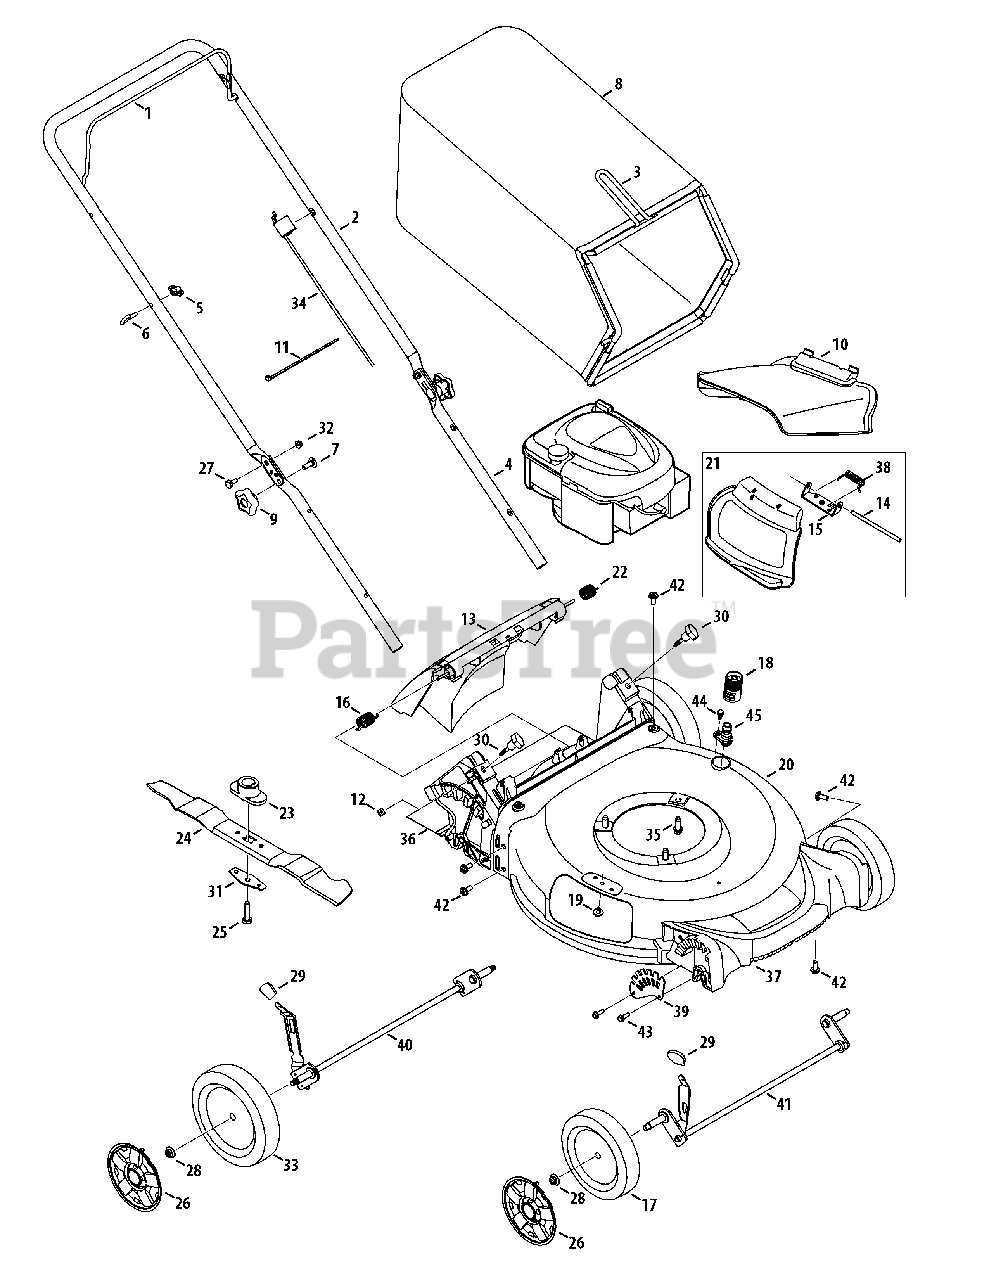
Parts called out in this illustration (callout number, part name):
1	Blade Control
2	Upper Handle
3	Grass Catcher Frame
4	Lower Handle
5	Wing Nut
6	Rope Guide
7	Carriage Screw, 5/16-18
8	Grass Bag
9	Hand Knob
10	Side Chute
11	Cable Tie
12	Nut, Sq., 1/4-20
13	Rear Discharge Door Assembly
14	Hinge Pin
15	Chute Deflector Bracket
16	Torsion Spring - RH
17	Wheel, 7 x 2
18	Water Nozzle Adapter
19	Screw, 1/4-20 x .500
20	Deck - 21"
21	Hinged Mulch Plug Assembly
22	Torsion Spring - LH
23	Blade Adapter
24	Mulching Blade
25	Screw , 3/8-24 x 1.50
26	Hub Cap - Front
26	Hub Cap - Rear
27	Sldr. Screw, .375 x .126 x 1/4-20
28	Flange Lock Nut, 3/8-16
29	Adjustment Lever Knob
30	Wing Knob
31	Blade Bell Support
32	Nut, Flange Lock, 1/4-20
33	Wheel, 8 x 2
34	Control Cable
35	TT Screw, 3/8-16 x 1.0
36	Trail shield
37	Front Cover
38	Torsion Spring
39	Front Height Adjuster Plate
40	Rear Axle Assembly
41	Front Axle Assembly
42	Screw, 5/16-14 x .750
43	Screw, 1/4-15 x .750
44	Screw, 1/4-20 x .500
45	Deck Wash Nozzle
